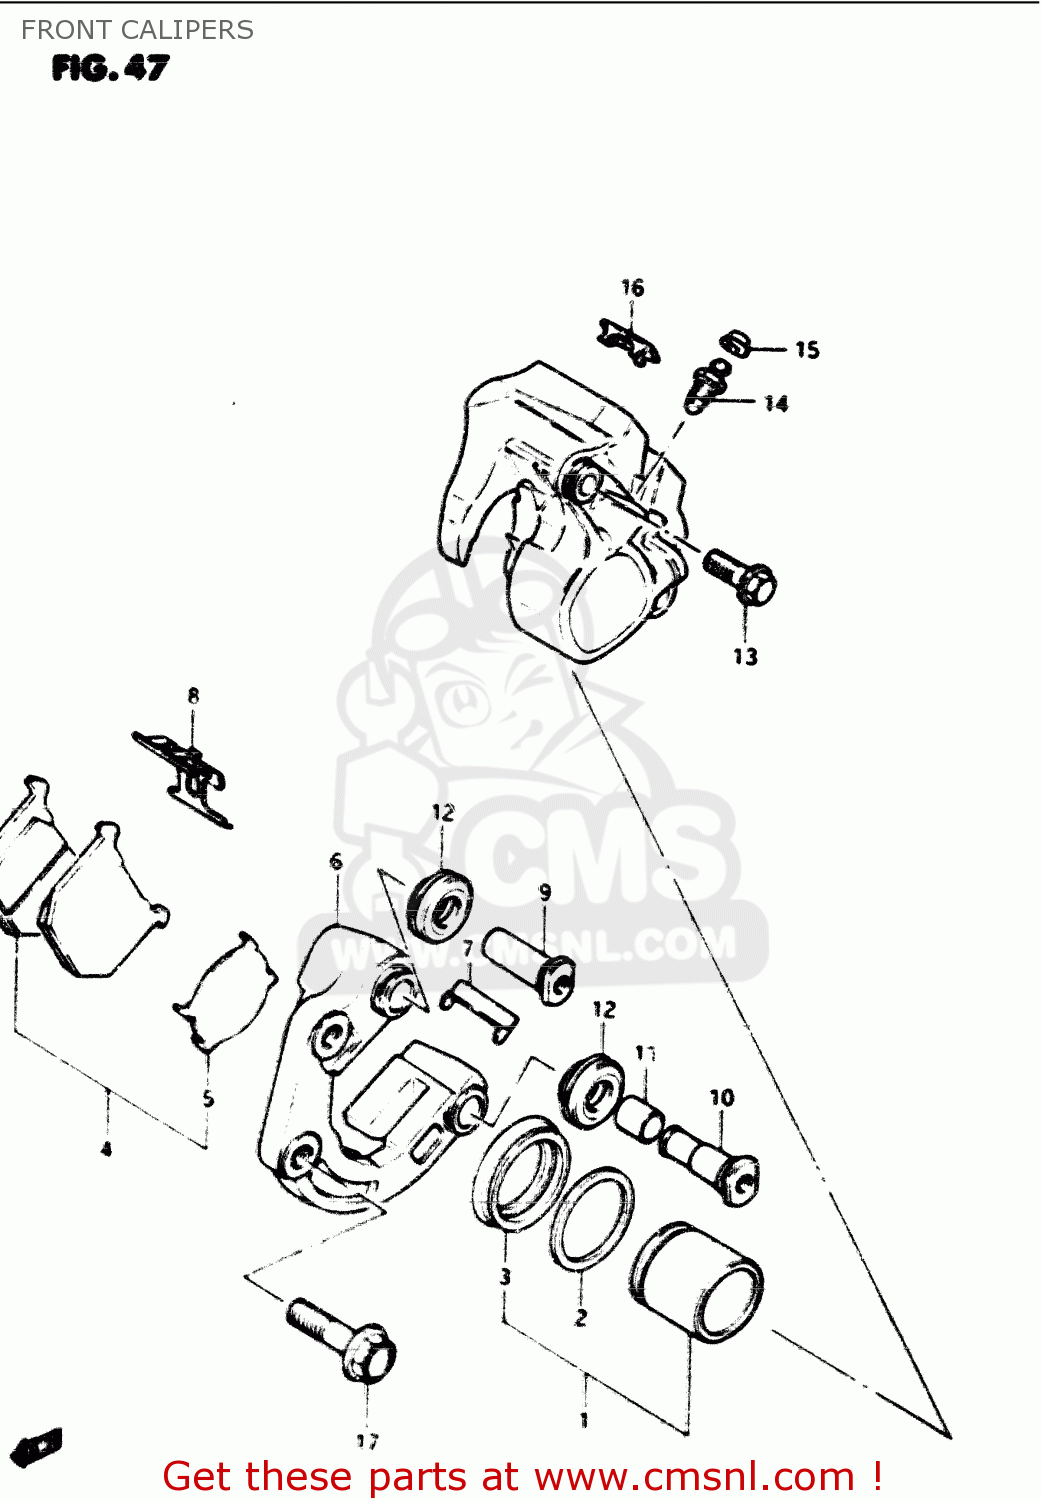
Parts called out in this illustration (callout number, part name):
1	PISTON SET
2	SEAL,PISTON
3	BOOT,PISTON
4	PAD SET,BRAKE (MCA)
5	SHIM,PAD
6	CARRIER,CALIPER,LEFT
7	GUIDE,PAD
8	SPRING,PAD
9	AXLE NO.1
10	AXLE NO.2
11	BUSH,AXLE
12	BOOT,AXLE
13	BOLT
14	BLEEDER
15	CAP,BREATHER
16	COVER
17	BOLT(10X37)
